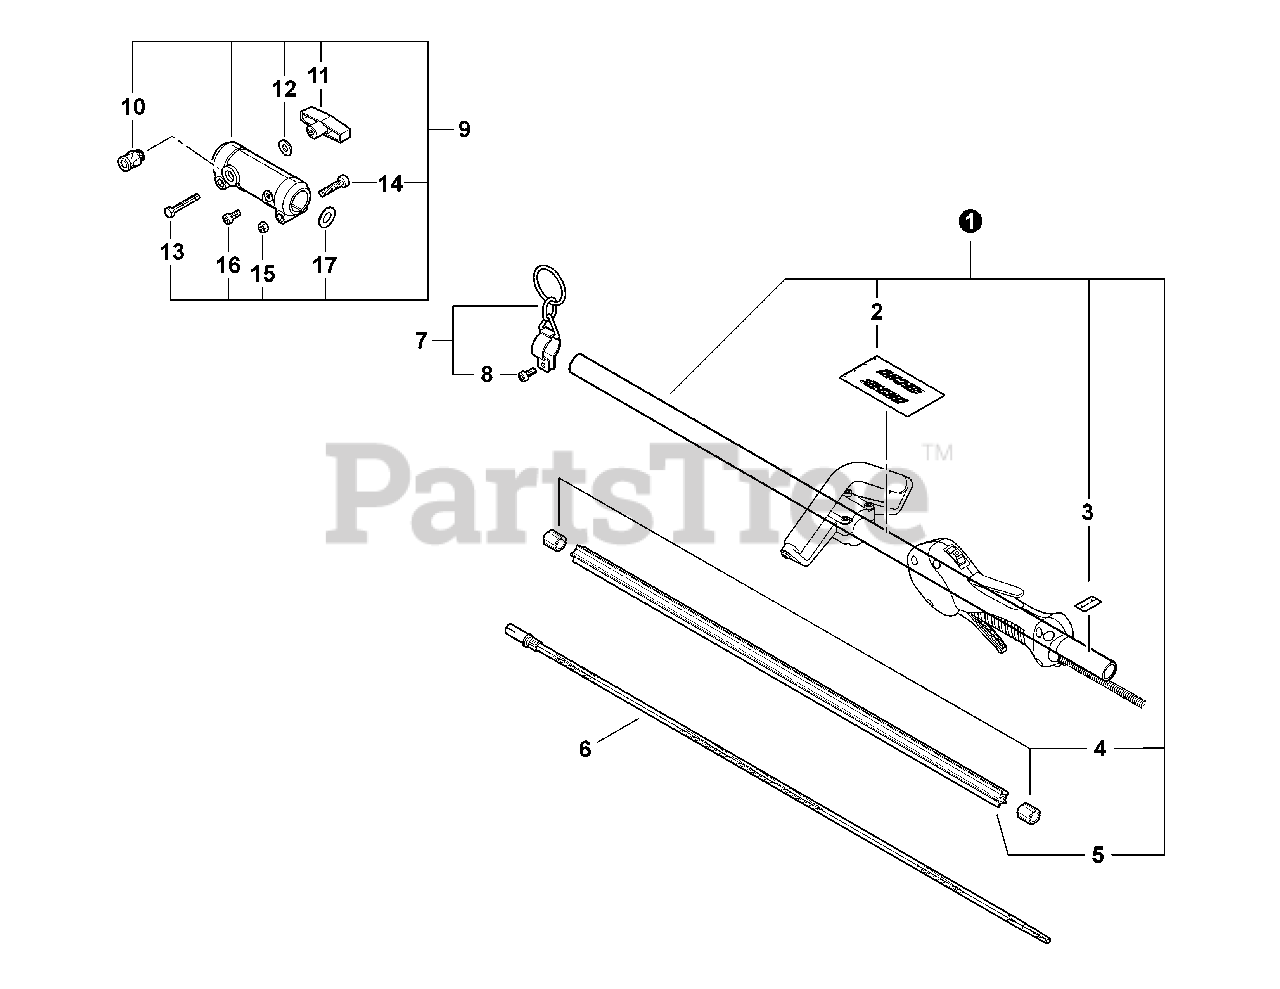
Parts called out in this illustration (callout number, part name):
1	MAIN PIPE ASSY
2	LABEL, HANDLE LOCATION
3	LABEL - ALIGNMENT
5	LINER - FLEXIBLE
6	DRIVESHAFT - FLEXIBLE
7	HANGER SET, HARNESS
8	BOLT, TORX 5×12
9	COUPLER ASSY
10	LATCH ASSY
11	KNOB, FASTENER
12	WASHER 6.6×20×1.6
13	BOLT 6×40
14	BOLT, TORX 6×25
16	BOLT, TORX 5×10
17	WASHER 18 SPR STEEL
